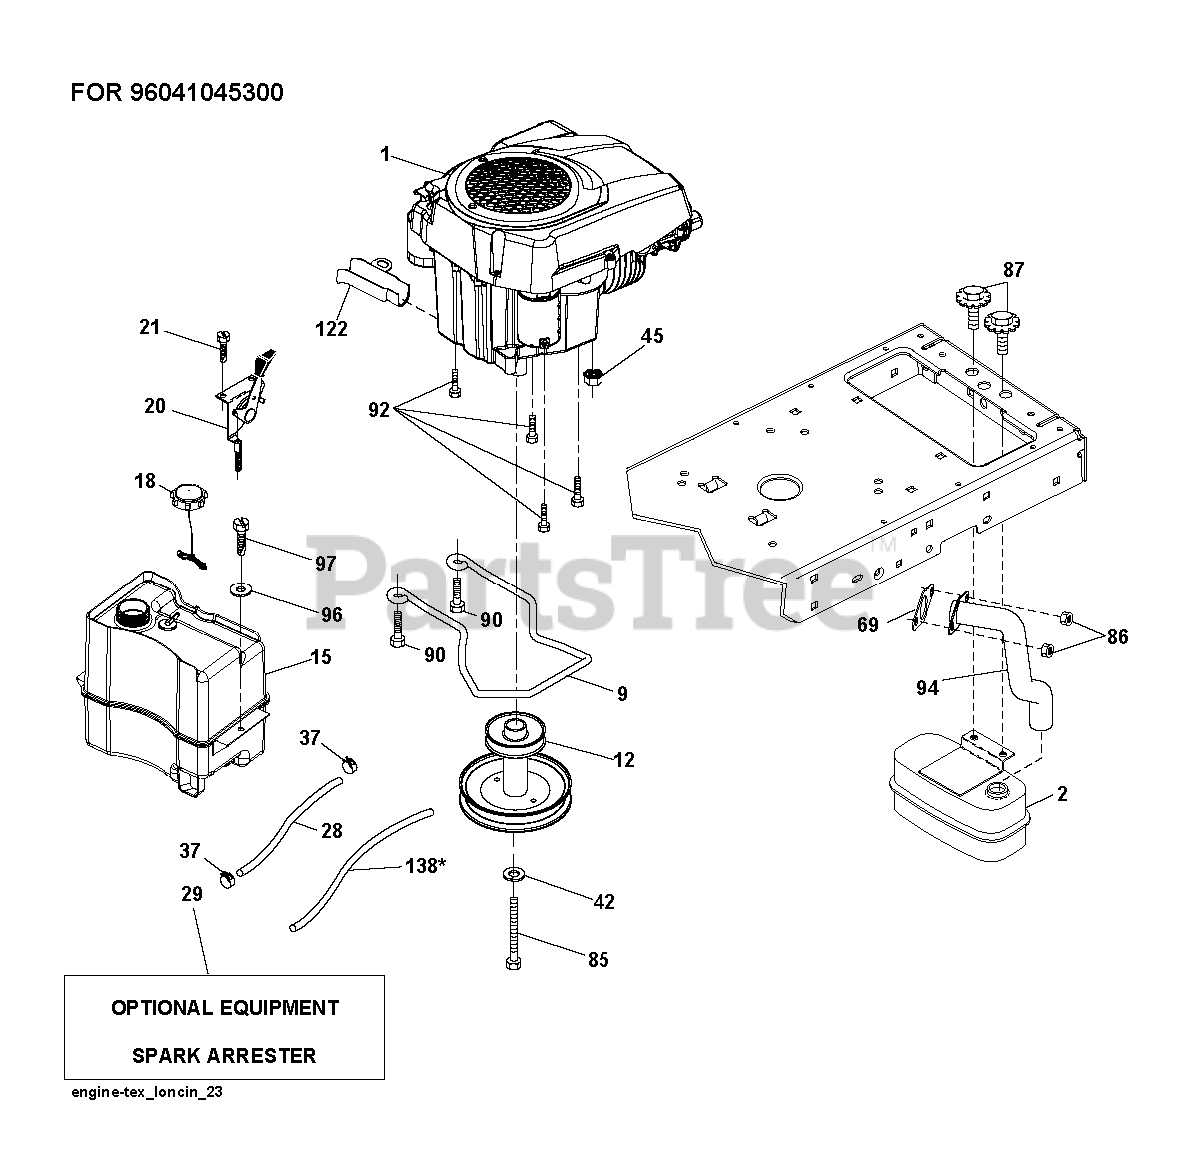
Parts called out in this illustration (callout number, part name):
1	RAIL, FRAME RH
2	DRAWBAR-GT
3	SIDE PANEL LH
4	Nut, Lock Hex 7/16 Unc
6	DASH ASS'Y LOWER
7	SCREW
8	SUPPORT, BATTERY
9	PAL NUT LT
14	HOOD ASM PNT
15	LENS LH
16	COVER ACCESS
17	SCREW
18	GRILL COMPLETE
19	WASHER
20	BOLT
22	PANEL ASM SD RH
23	SCREW GTV
24	FOOTREST RH
25	LENS RH
27	NUT
28	FOOT REST LH
29	DASH SUPT YP
30	SADDLE.HYDRO.95
31	BRACE, SUPPORT STEERING
32	FRAME PIVOT BRKT ASSY LH
33	FRAME PIVOT BRKT ASSY RH
34	ENGINE SUPPORT BRKT
35	WASHER
36	BOLT.FIN.HEX.5/16-18X3/4
37	FENDER
38	LOCKWASHER
39	FRONT AXLE BRACKET
40	AXLE SUPPORT BRKT
43	FRONT SUSPENSION BRKT LH
44	FRONT SUSPENSION BRKT RH
45	BRACKET SUSP RH
50	BRACKET, CHASSIS FRONT
52	NUT.71038.31-18.HEX.NYLOCK
54	NUT
56	BRACKET ASM, SUSP CHASSIS
58	FENDER BRKT
60	SCREW
63	WASHER
68	Screw 5/16-18 x 1/2 Hex, Self Tapping 5/16-18 x 1/2
70	BELT GUIDE
72	Screw, Machine, Truss Head 5/16-18 UNC x 3/4
74	SCREW
76	WELDNUT
79	RP SCREW
82	NUT **
84	MOWER STOP
86	BOLT
90	LOCKWASHER
91	RAIL, FRAME LH
92	DASH PLATE
95	NUT-PUSH YT
98	BRACKET CHASSIS
99	ROD ASMBLY BYPASS
100	CAP
101	SCREW LT
102	RETAINER M
103	BRACKET LOCK BYPASS
106	SCREW
107	LATCH.HOOD.
108	SNAP CAP LT
110	PIVOT ASM GRL/HD
112	NUT
114	BOLT.3/8-14X1.25
115	BUMPER ASM
116	BRACKET BUMPER
117	PLUG PLASTIC
118	WASHER
120	WASHER
130	Screw, SLTD Hex Hd. W/Pl Washer
131	BRACKET.SUPPORT.HOOD/PANEL.NLA
132	SCREW 10-24X3/8
